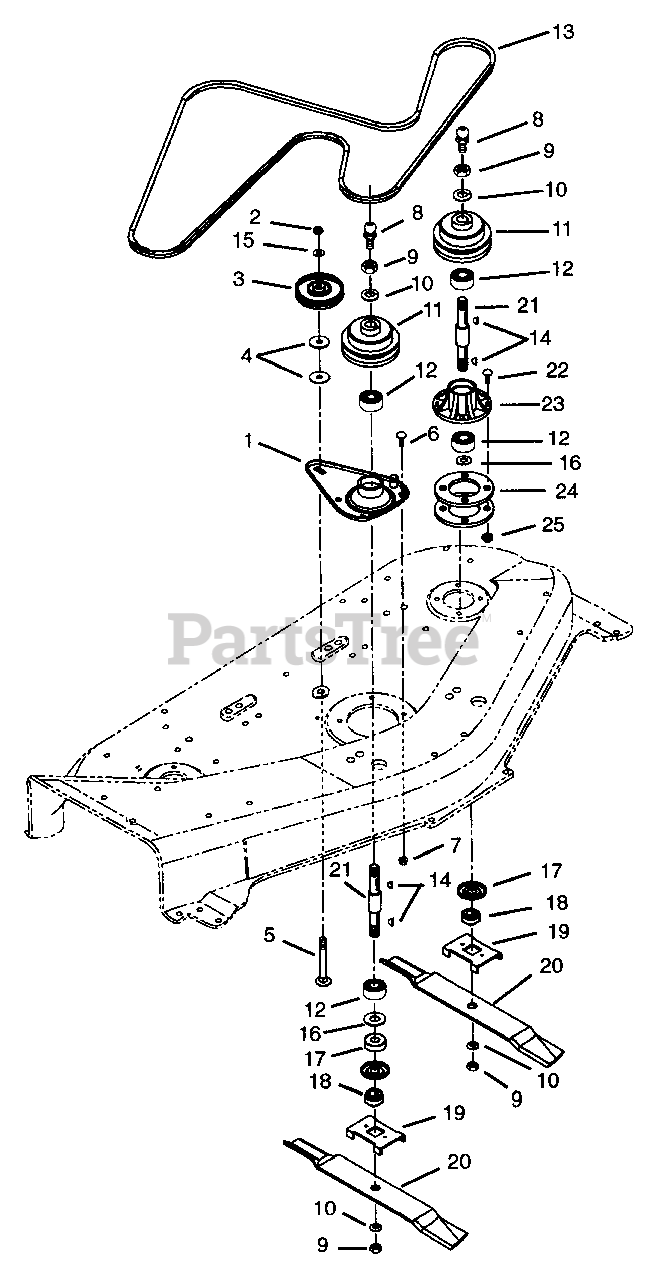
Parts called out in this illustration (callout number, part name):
1	HOUSING, SPINDLE
2	NUT-LK-NYL .375-16 PL
3	IDLER-FLAT 4.00 X .38 NWHAMSHR
4	WSHR-HDND-THR .390X1.50X.125PL
5	BLT-RDHDSQNK .38-16X2.00
6	BLT-RDHDSQNK .38-16X.62 GR5 PL
7	NUT-LK-CTR .375-16 GR A PL
8	FTG-LUBE .25-28X.256 YWZC
9	NUT-JAM .75-10 PL
10	WSHR-LK .750X.188 MED PL
12	BRG-BALL .750X1.781X.61
13	V-BELT, HA-RAW EDGE
14	KEY-WDRF .188X.625X.25 SAE 61
15	WSHR-FL-STL .38X.875X.083 PL
16	WSHR-FL-STL .754X1.000X.032
17	BEARING SLINGER
18	RETAINER HUB
19	BLADE TRAY 48
21	SPINDLE SHAFT W/ZERK
22	BLT-RDHDSQNK .375-16X.75 PL
23	SPINDLE HOUSING
24	SPACER, SPINDLE
25	NUT-LK-JAM-CTR .375-16 PL
26	V-BELT, HA-RAW EDGE
27	FTG,LUBE 1/8
